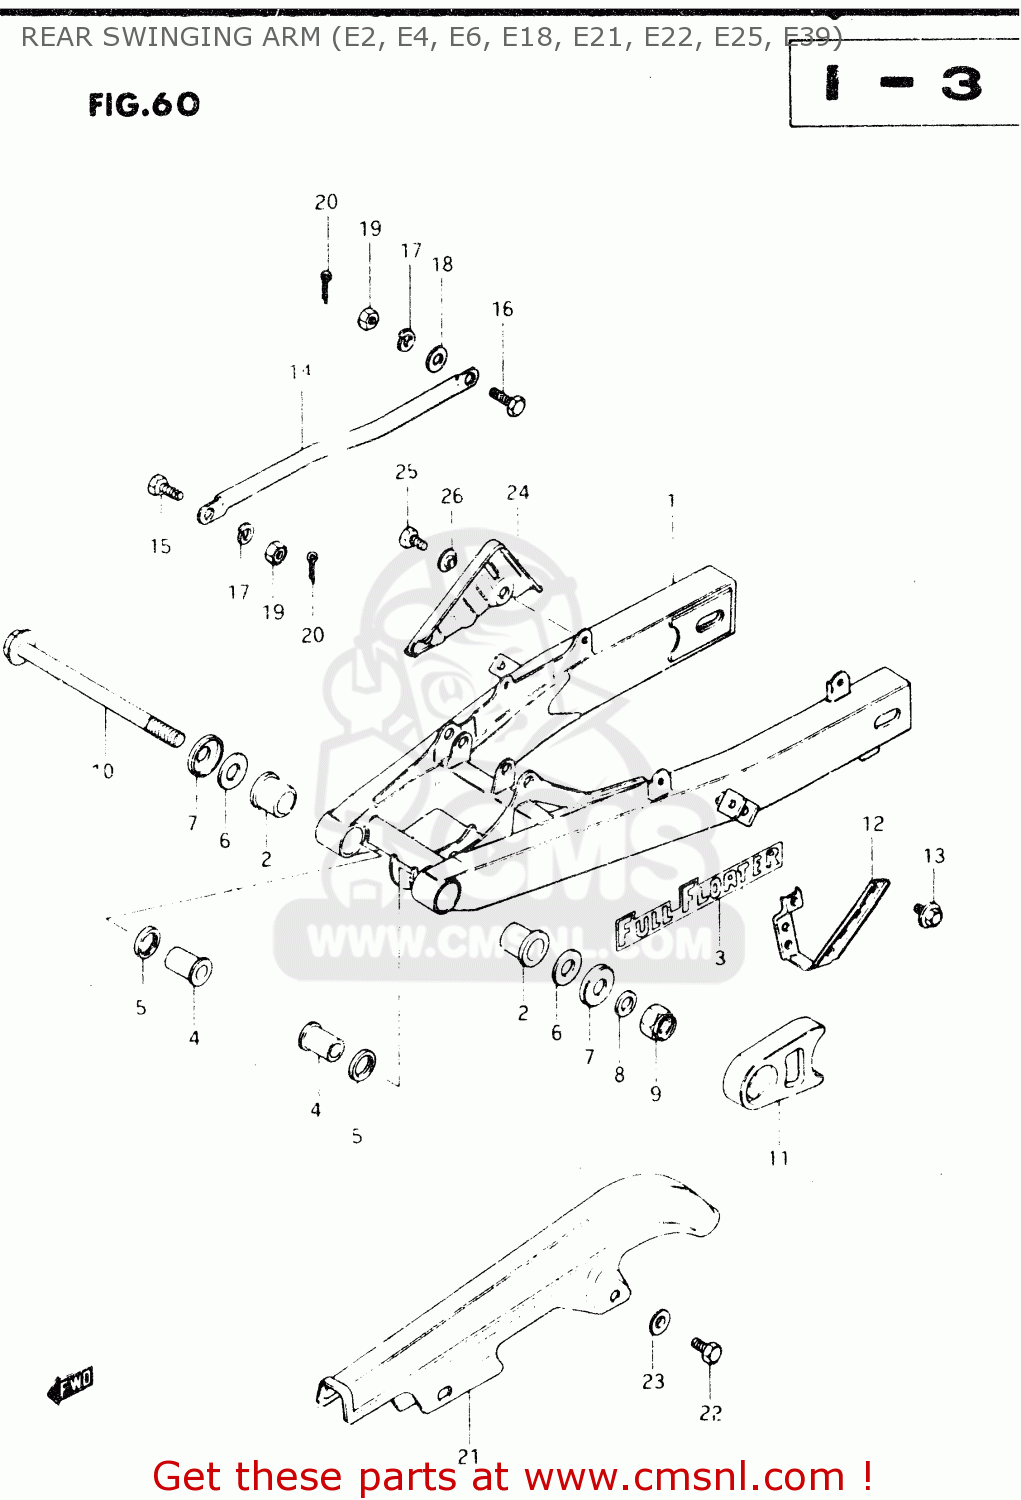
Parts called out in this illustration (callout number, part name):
1	SWINGING ARM, REAR
2	BUSHING,RR SWGARM PIVOT
3	EMBLEM
4	SPACER,RR SWGARM PIVOT OUTER
5	SEAL,OIL(20X27X5)
6	WASHER
7	COVER,REAR SWING ARM DUST
8	WASHER
9	NUT 14MM
10	SHAFT,REAR SWING ARM
11	BUFFER,CHAIN TOUCH DEFLECTOR
12	GUIDE,CHAIN
13	BOLT 8X12
14	LINK,REAR TORQUE
15	BOLT(8X22.5)
16	BOLT(8X26.5)
17	LOCK WASHER
18	WASHER
19	NUT
20	PIN 20X20
21	CASE,CHAIN
22	BOLT 6X8
23	WASHER
24	GUARD,PILLION FOOT
25	BOLT 6X8
26	WASHER
